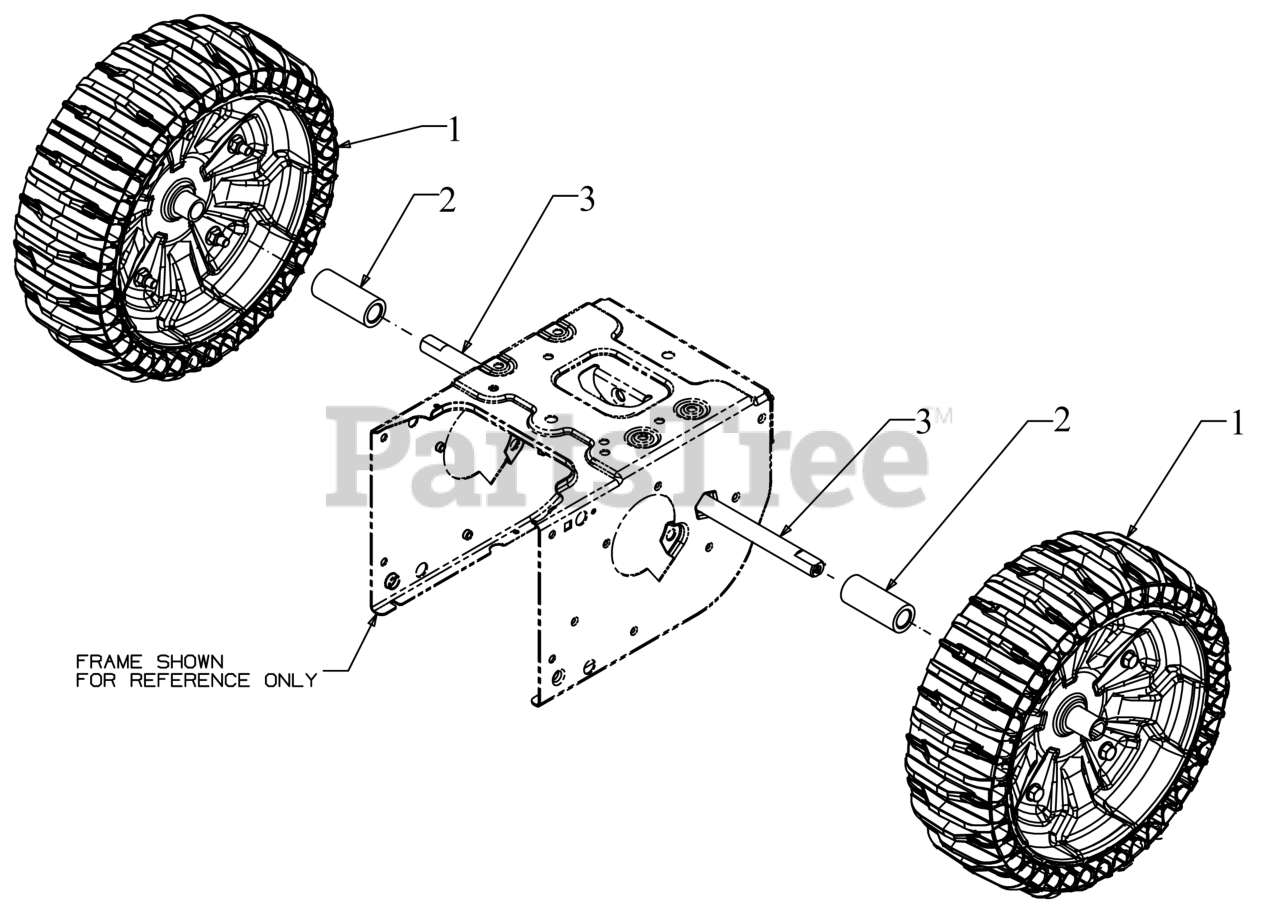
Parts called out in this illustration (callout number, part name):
1	Genuine Factory Parts AIRLESS SNOW THROWER TIRE SET 15X5
2	WHEEL SPACER 1.25ODX.75X3.00
3	AXLE .75OD x 11.12LG
